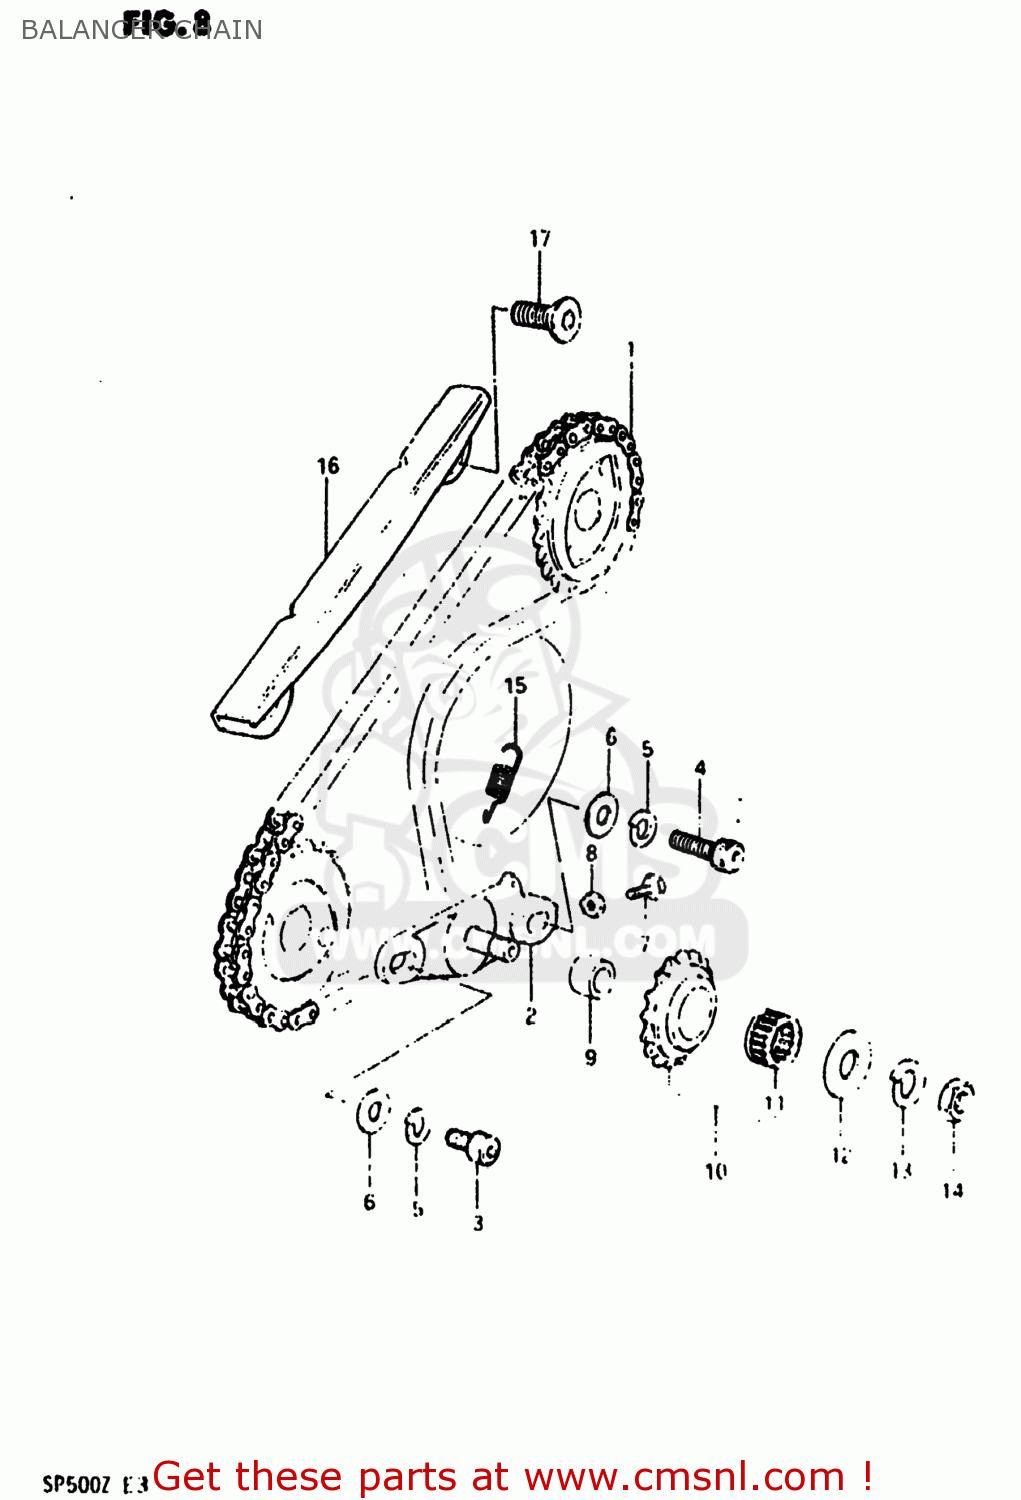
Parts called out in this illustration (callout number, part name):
1	GOVERNOR ASSEMBLY,EXHAUST
2	BRACKET,BALANCER CHAIN TENSIONER
3	BOLT(8X22)
4	BOLT
5	LOCK WASHER
6	WASHER
7	BOLT 5X20
8	NUT
9	SPACER,TENSIONER SPROCKET
10	ROD,EXHAUST VALVE
11	BEARING(17X23X12)
12	WASHER
13	WASHER,LOCK 12
14	NUT
15	SPRING
16	GUIDE,BALANCER CHAIN
17	SCREW
